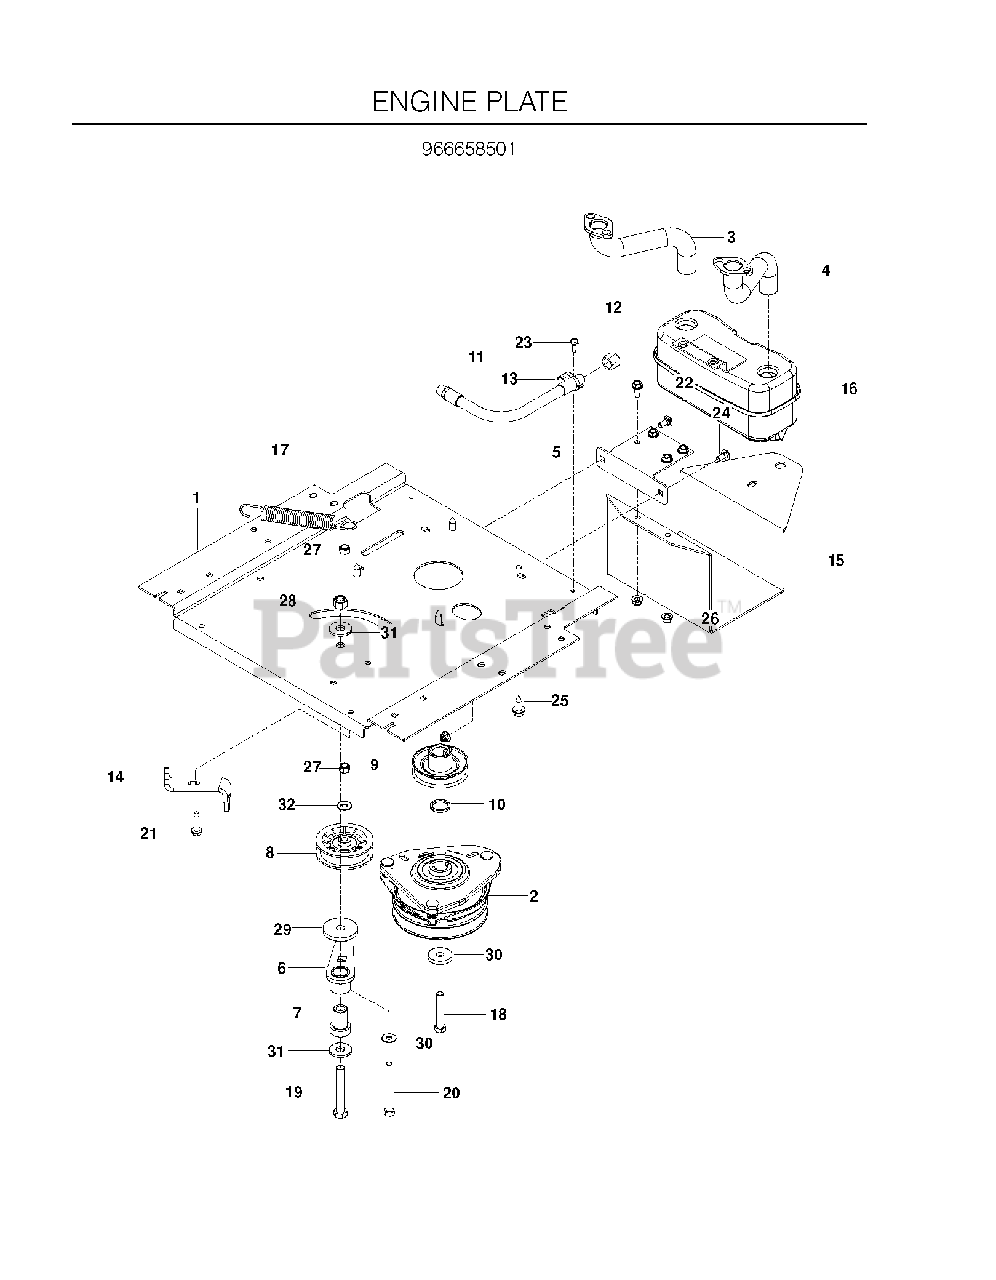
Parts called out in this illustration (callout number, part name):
1	PLATE, ENGINE WIDE, BLACK
3	PIPE-EXHAUST LH
4	PIPE-EXHAUST RH
5	BRACKET, MUFFLER, BLACK
6	IDLER ARM
7	IDLER SPINDLE
8	PULLEY, IDLER
9	PULLEY, ENGINE
10	HUB PULLEY SPACER
11	OIL DRAIN HOSE
12	DRAIN CAP
15	GUARD, MUFFLER, BLACK
16	MUFFLER ASM TWIN
17	SPRING, DECK DRIVE
18	HCS 7/16-20 X 2.5 GR8
19	HCS 1/2C X 3 1/4
20	HCS 3/8-16X3 1/2 GR5
21	BOLT 3/8-16 X 1 1/2 ZINC CLEAR
22	BOLT 5/16-18 X 3/4
23	SCREW 1/4 X 5/8
24	BOLT 5/16C X 3/4" CARRIAGE
25	HHFS 3/8-16 X 1.0 THD FORMING
26	5/16-18 NYLOC FLANGE NUT
27	NUT 3/8-16 NYLOC
28	NUT 1/2-13 HEX NYLOC ZD
29	HEAVY WASHER
31	WASH USS FLAT 1/2
32	WASHER 5/16 FLAT
